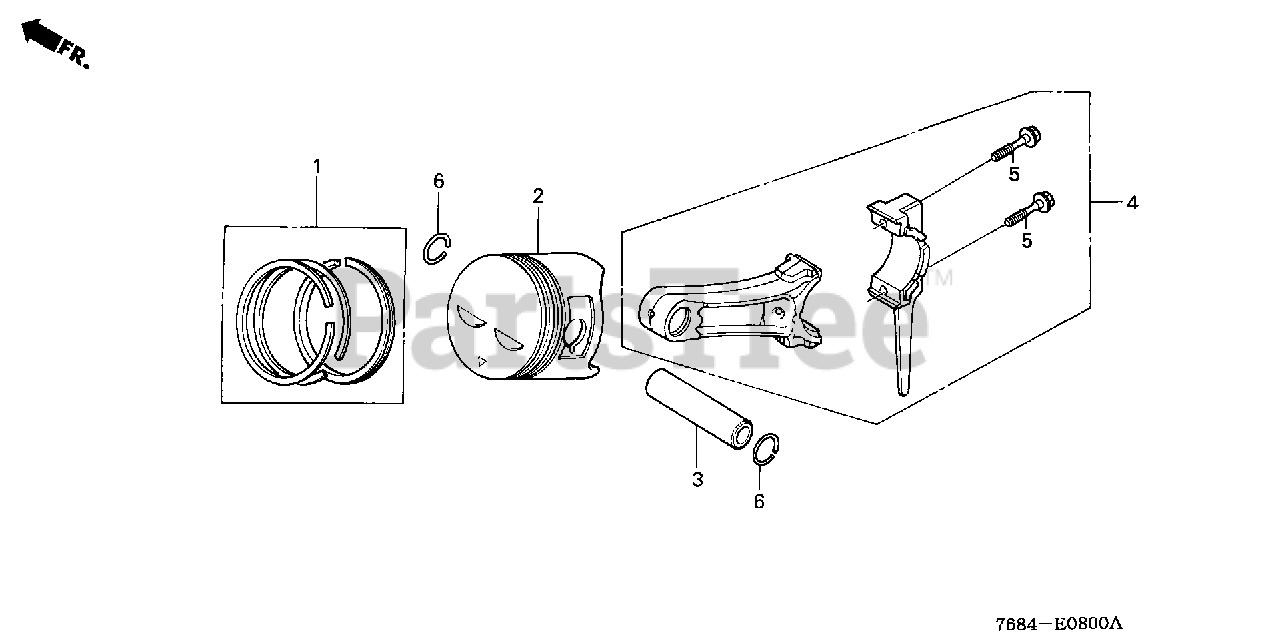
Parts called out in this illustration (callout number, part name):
1	RING SET, PISTON (STD) (NIPPON)
1	RING SET, PISTON (0.25) (NIPPON)
1	RING SET, PISTON (0.50) (NIPPON)
1	RING SET, PISTON (0.75) (NIPPON)
1	RING SET, PISTON (0.75) (TEIKOKU)
2	PISTON (STD)
3	PIN, PISTON
4	ROD ASSY., CONNECTING (STD)
5	BOLT, CONNECTING ROD
6	CLIP, PISTON PIN (18MM)
